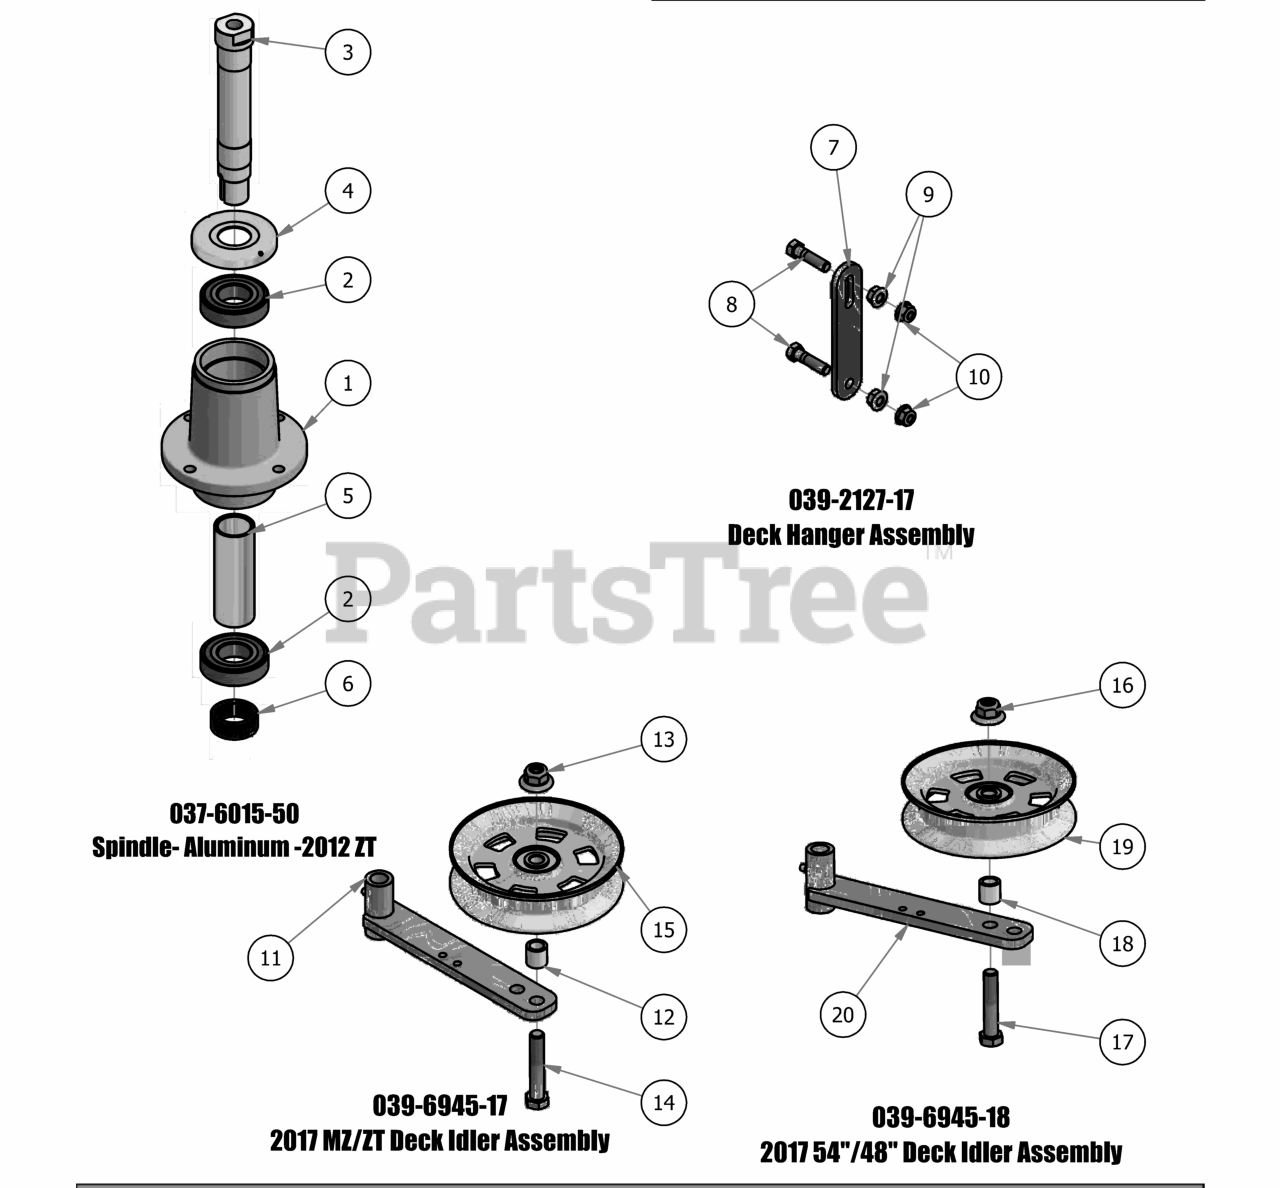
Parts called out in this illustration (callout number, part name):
1	Aluminum Spindle Housing -2010
2	Spindle Bearing, 2004 and up
3	Short Spindle Shaft w/Locking
4	Dust Cover
5	Tube Spacer for Spindle Shaft
6	Collar Spacer - Top of Spindle
7	2017 MZ/ZT Deck Hanger
8	3/8" x 1 1/2" Hex Bolt
9	3/8" Flange Nut
10	3/8" Nylock Flange Nut
11	Deck Idler
12	Spacer 3/4 OD x 1/2 ID x 3\4 Length
13	1/2-13 Nylon Flange Nut
14	1/2" x 2 3/4" Hex Bolt
15	5" Idler Pully
16	1/2-13 Nylon Flange Nut
17	1/2" x 2 1/2" Hex Bolt
18	Spacer 3/4 OD x 1/2 ID x 3\4 Length
19	5" Idler Pully
20	Deck Idler
